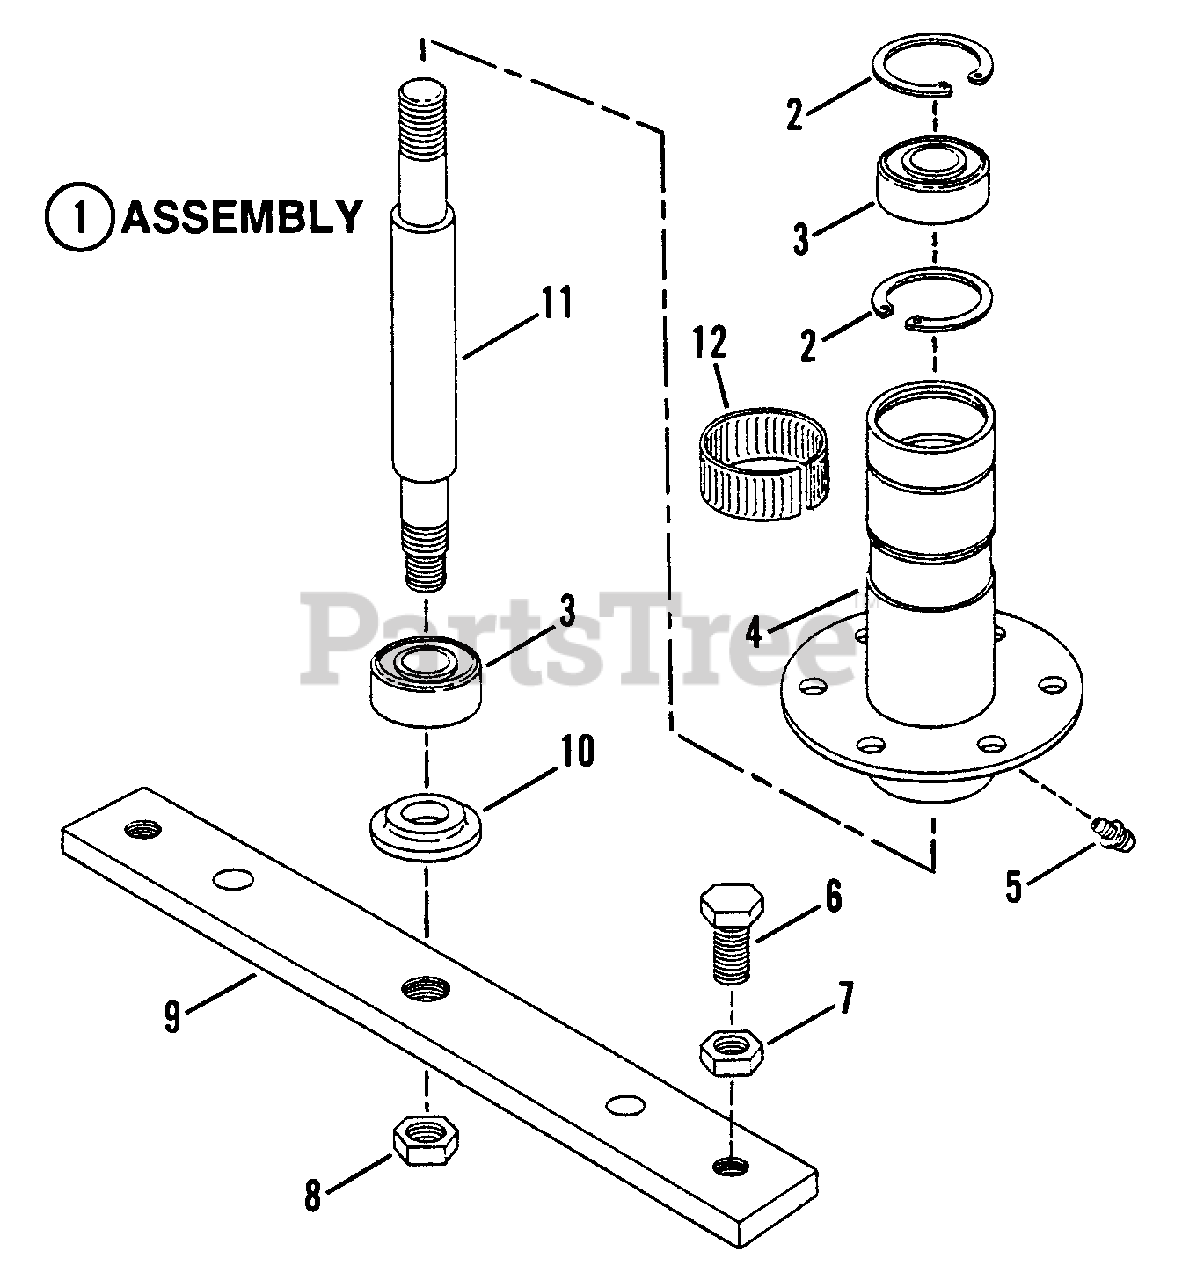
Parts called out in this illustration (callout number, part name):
1	ASSEMBLY, Spindle Housing, 33" Cutting Deck
2	RING, Retaining
3	BEARING, Spindle
4	HOUSING, Spindle
5	FITTING, Lube (Press fit for .187 hole-no ball)
6	SCREW, 1/2-20 x 1" Hex Head Cap, Grade 5
7	NUT, 1/2-20 Hex Jam
8	NUT, 5/8-18 Hex Lock
9	HOLDER, Blade
10	WASHER, Spindle
11	SPINDLE (7.64")
12	RING, Tolerance
